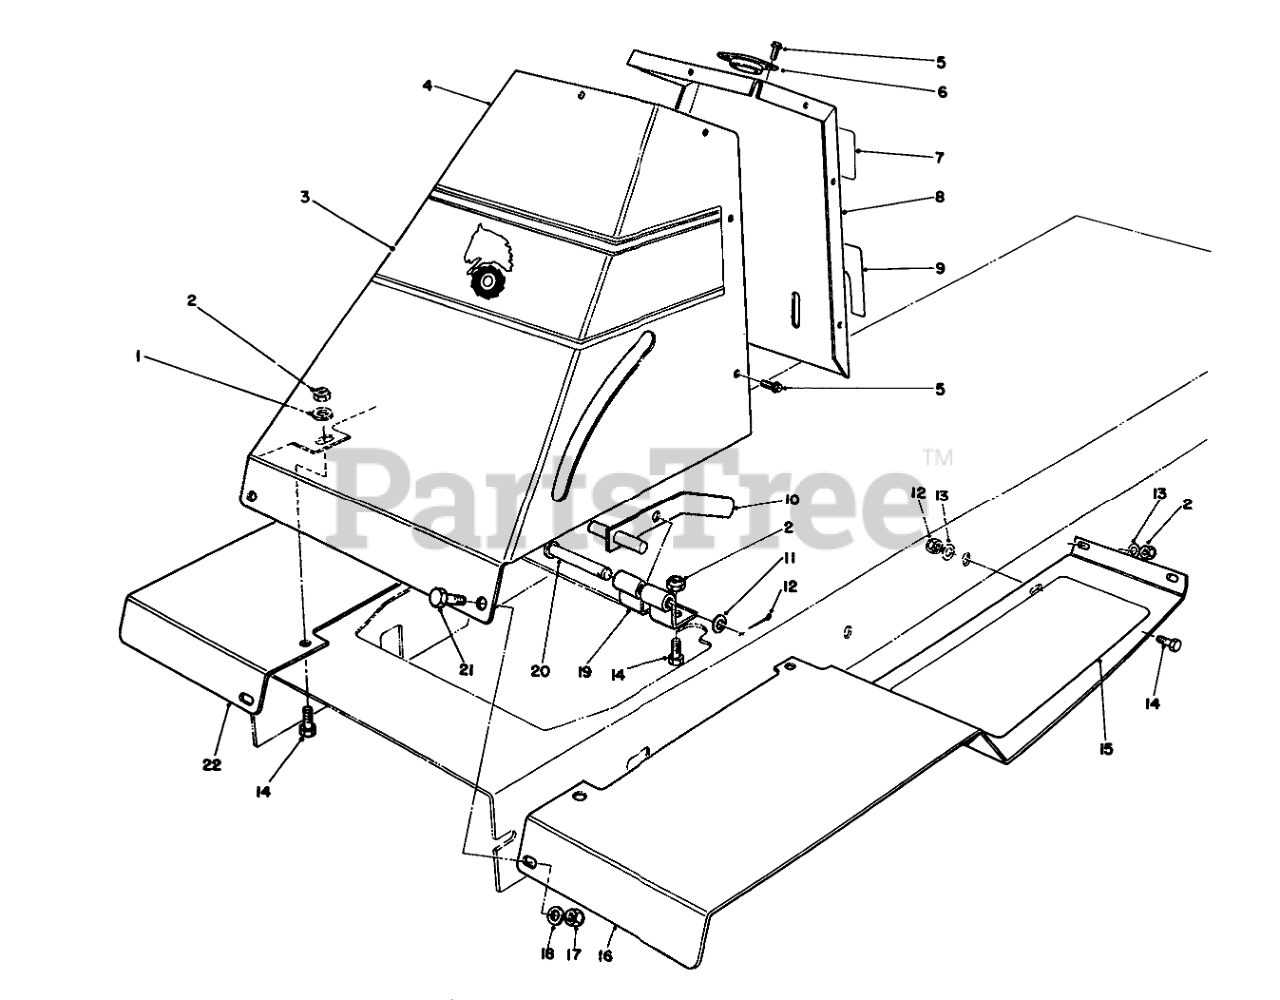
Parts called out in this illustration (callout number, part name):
1	WASHER-FLAT
2	NUT-LOCK, NI
3	DECAL - STEERING SUPT
4	Tower-Front
5	SCREW-HWHTF
6	GUIDE-STRG SHAFT
7	DECAL-DANGER
8	Tower-Rear
9	PARK BRAKE DECAL
10	PARKING BRAKE WA B
11	WASHER-FLAT
12	PIN-COTTER
13	WASHER-PLAIN
14	SCREW-HH
15	FOOT TREAD L.H.
16	Footrest-LH
17	NUT-LOCK, NI
18	WASHER-FLAT
19	Bracket-Parking Brake
20	PIN-CLEVIS
21	SCREW-HH
22	Footrest-RH.
